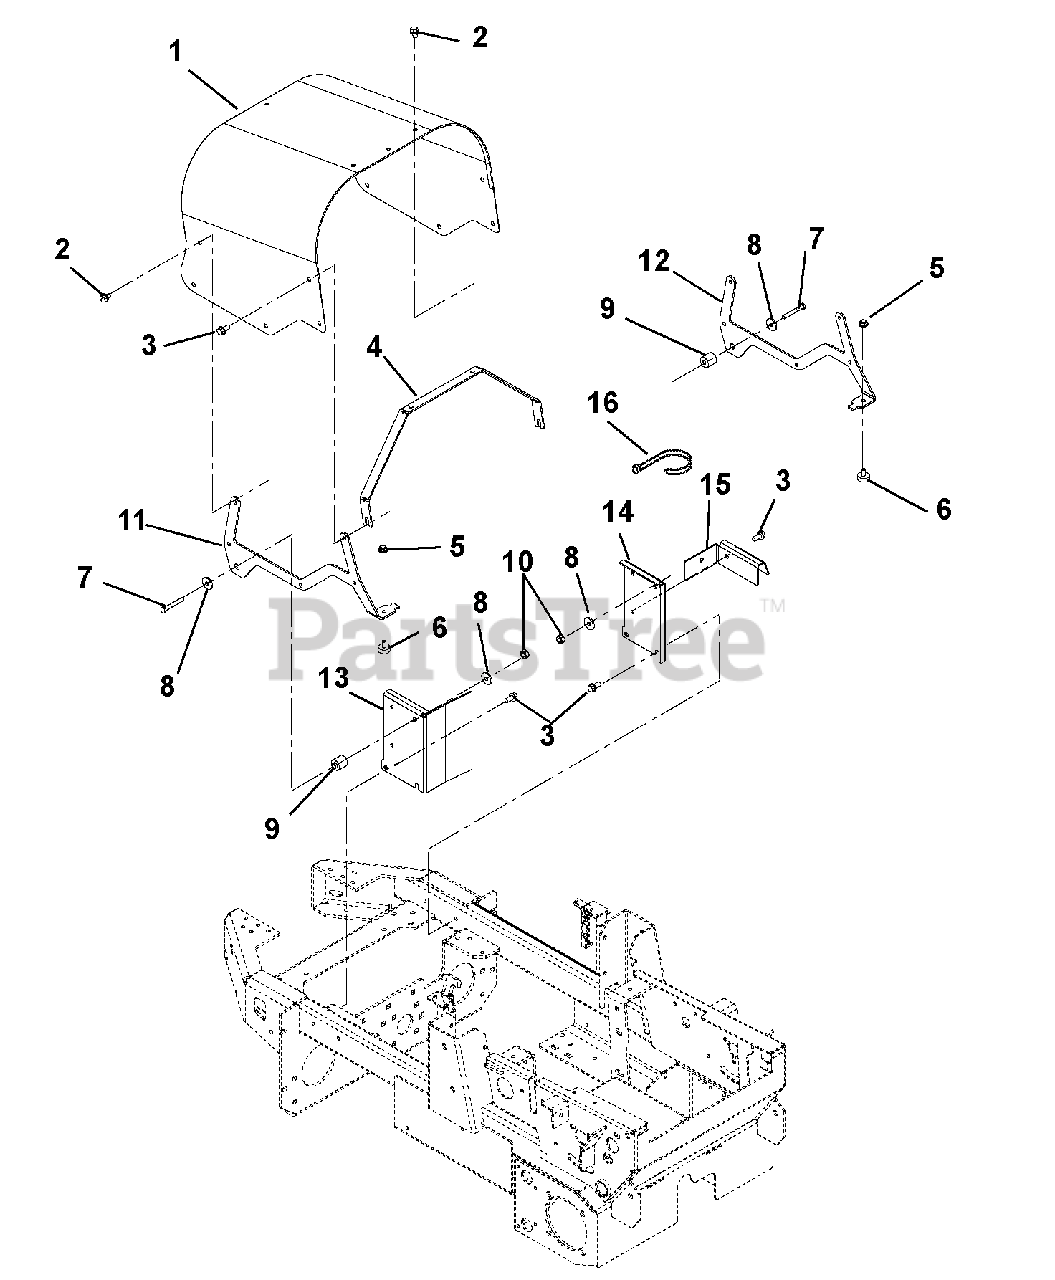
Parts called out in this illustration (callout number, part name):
1	Hood, Outfront Rapid XZ
2	Screw, Tapping .38-16 x .50 Hex Washer Head Thread
3	Screw, Tapping .38-16 x .75 Hex Washer Head Thread
4	Support, Lateral Hood
5	Nut, Spin Lock-Flange .312-18
6	Bumper, Rubber
7	Bolt, Hex .31-18 x 2.25 Grade 5
8	Washer, Flat-Steel .344 x 1.125 x .135
10	Nut, Locking-Center .31-18
11	Bracket, Hood Left Hand
12	Bracket, Hood Right Hand
13	Bracket, Hood Support #2
14	Bracket, Hood Support #1
15	Cover, Wire
16	Wire Tie (Clutch wire to wire cover.)
